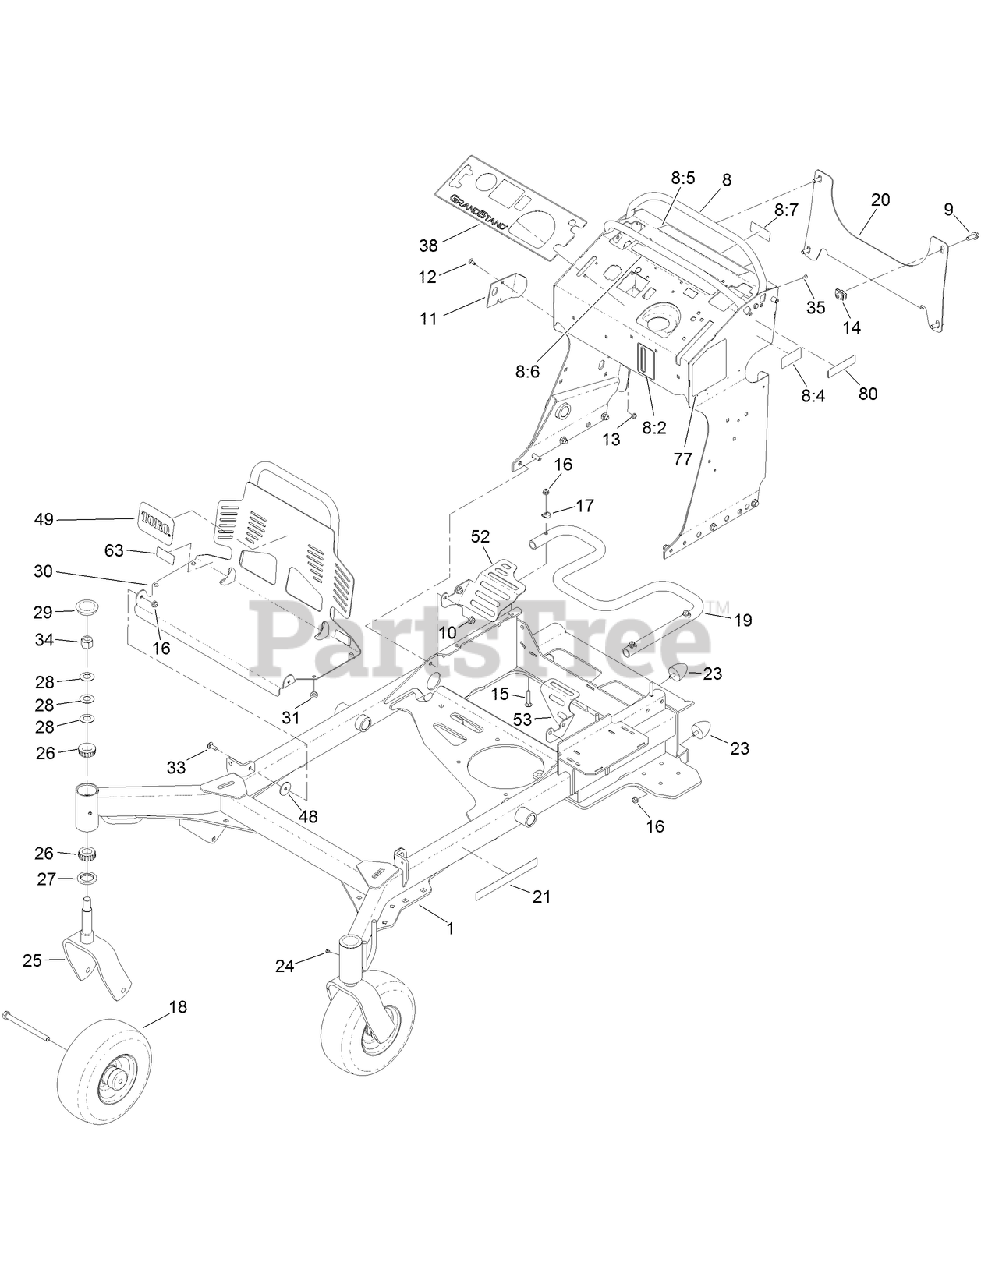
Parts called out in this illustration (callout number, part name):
8	TOWER DECAL ASM
8:2	DECAL-LEVEL, OIL
8:4	DECAL-FILL, FUEL
8:5	DECAL-CAUTION
8:6	DECAL-CONTROLS
8:7	DECAL-FUSE
9	SCREW-HHF
10	NUT-HF, NI
11	PLATE-STRIKER
12	SCREW-CARR
13	NUT-HF
14	NUT-TINNERMAN
15	BOLT-CAR
16	NUT-HF, NI
17	WASHER
18	WHEEL/TIRE AND BEARING ASM
19	TUBE-MOUNT, FUEL TANK
20	BRACKET-CROSS
21	DECAL-COMMERCIAL
23	BUMPER-RUBBER
24	FORK-CASTER
26	BEARING-ROLLER, TAPERED
27	SEAL-GREASE
28	WASHER-BELLVILLE
29	CAP-GREASE
30	GUARD-ENGINE
31	BUMPER
33	BOLT-CARR
34	NUT-LOCK, NI
35	RIVET-POP
38	DECAL-PANEL, CONTROL
48	WASHER-NYLON
52	GUARD-FAN, RH
53	GUARD-FAN, LH
63	DECAL-WARNING, NO RIDERS
77	DECAL-SERVICE AID
80	DECAL-ARRESTOR, SPARK
